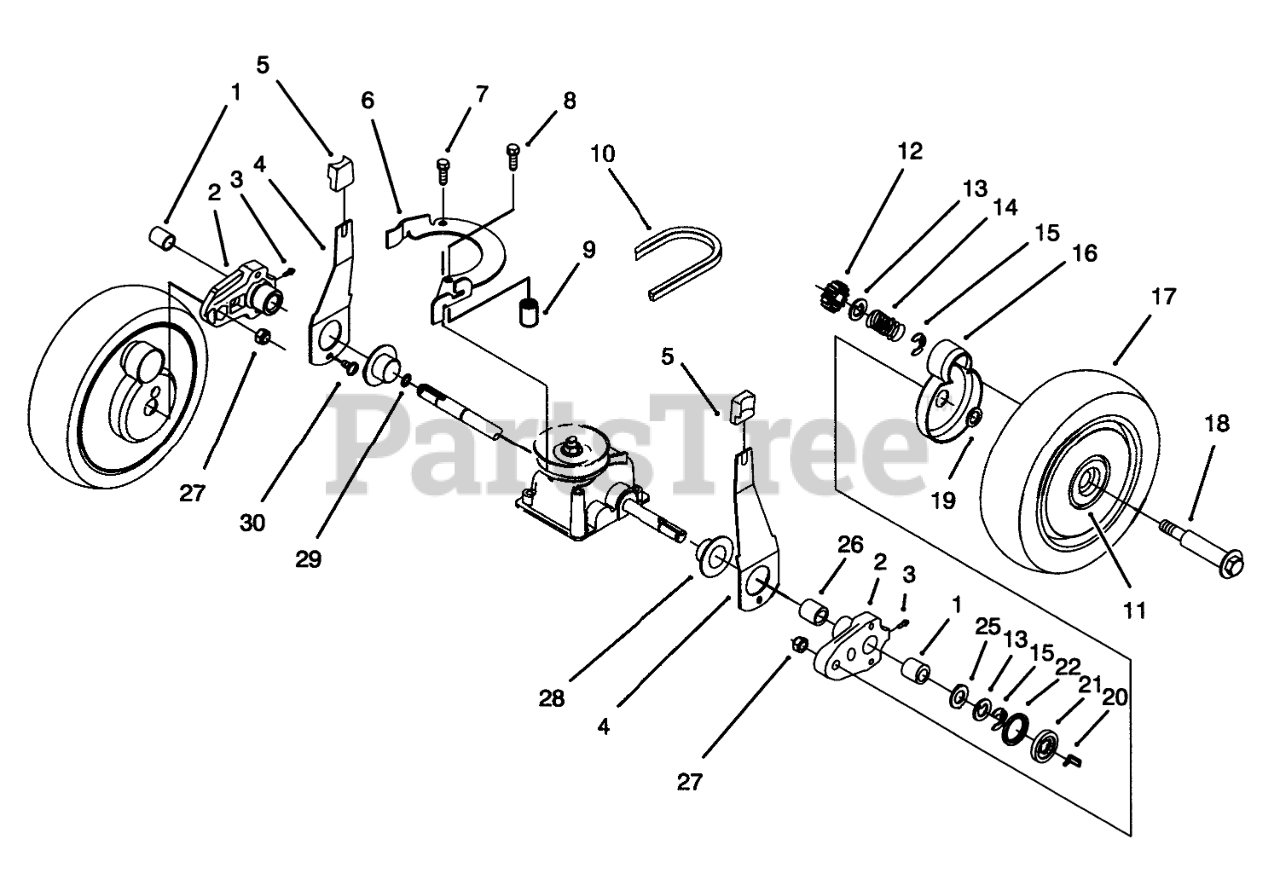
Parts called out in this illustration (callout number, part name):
1	BEARING-ROLLER
2	Pivot Arm Assembly (Incl. Ref. #1, 3, & 26)
3	FITTING-GREASE
4	SPRING ARM ASM SP
5	KNOB-ARM
6	BRACKET-BELT GUIDE
7	SCREW-HWHTF
8	SCREW-HWHTF
9	BUSHING-PLATE, ACTUATOR
10	BELT-V
11	BUSHING
12	GEAR-PINION
13	WASHER-THRUST, KEYED
14	SPRING-COMPRESSION
15	RING-CLIP, LOCKING
16	COVER-WHEEL
17	Wheel-Tire & Gear Ass-y (Incl. Ref. #11)
18	BOLT-WHEEL
19	SPACER-COVER, WHEEL
20	KEY-ROCKING, LH
21	WASHER-CLUTCH
22	RING-FRICTION
25	WASHER-ARM, PIVOT
26	BUSHING
27	NUT-LOCK
28	CAP-END
29	O-RING
30	SCREW-HWH
